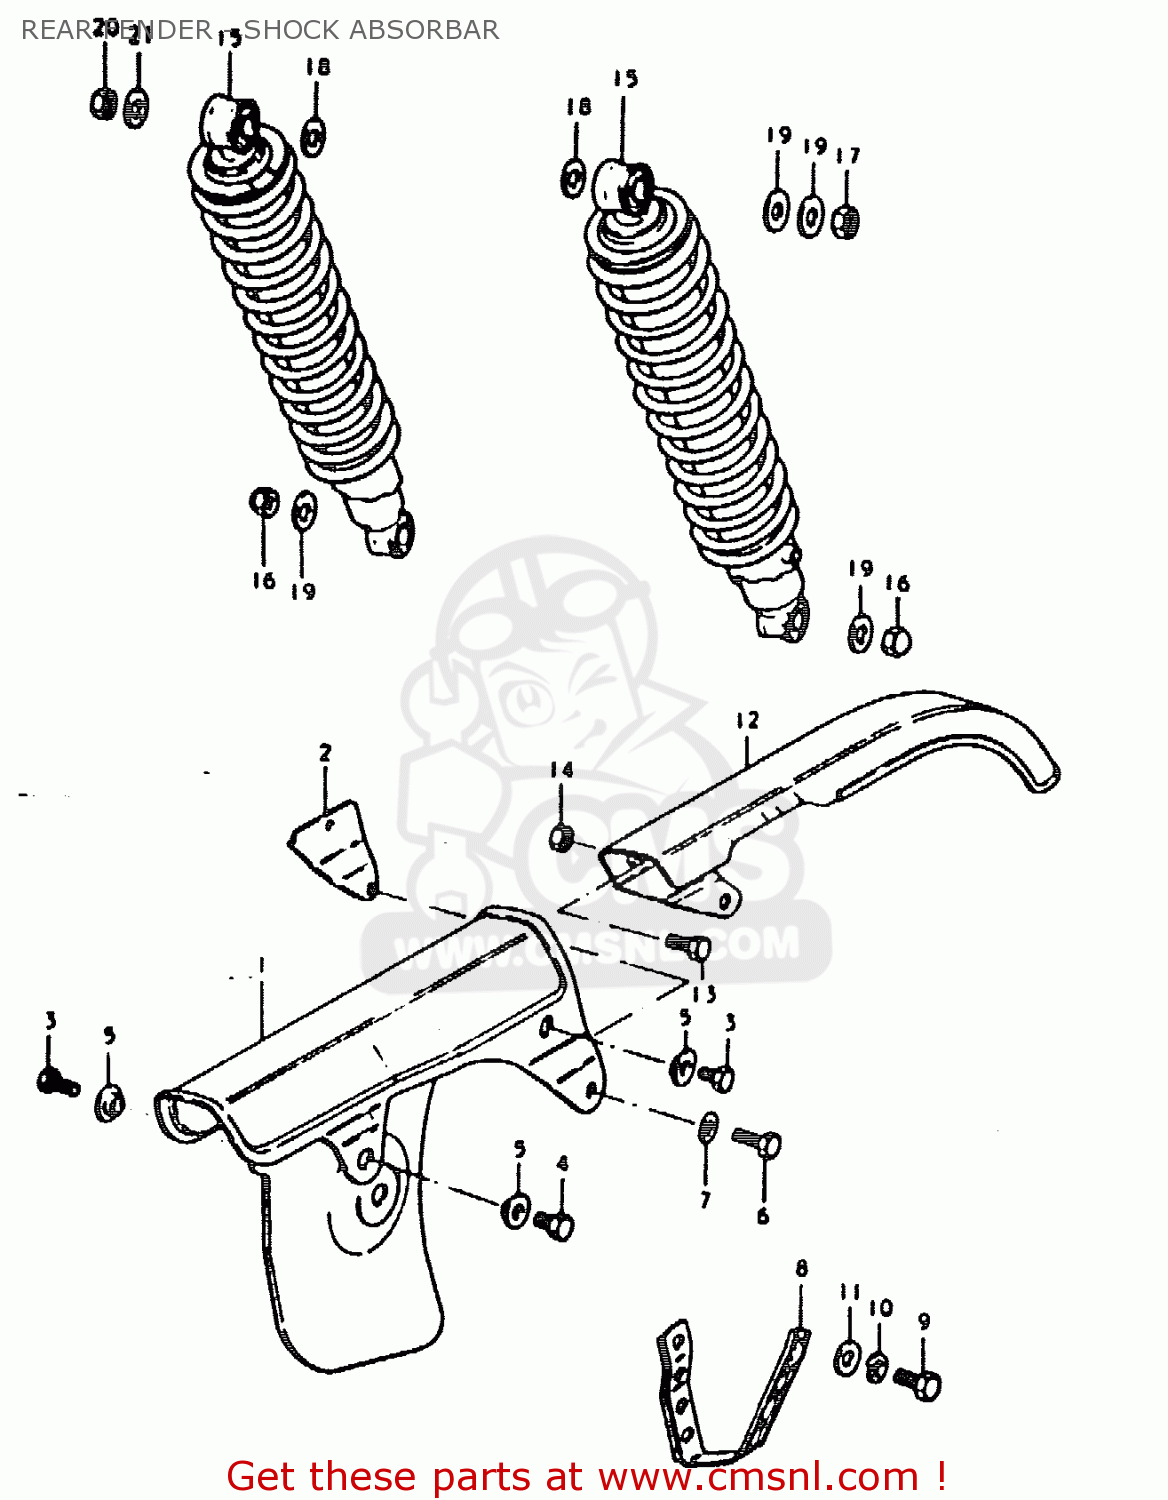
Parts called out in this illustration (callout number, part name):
1	CHAIN CASE
2	REINFORCEMENT,CHAIN
3	BOLT(6X8)
4	BOLT
5	WASHER
6	BOLT, UPPER
7	WASHER
8	GUIDE,CHAIN
9	BOLT 8X12
10	LOCK WASHER
11	WASHER
15	SHOCK ABSORBER ASSY, REAR
16	NUT, LOWER LH
17	NUT
18	WASHER
19	WASHER
20	NUT
21	WASHER (12.5X24X3.2)
